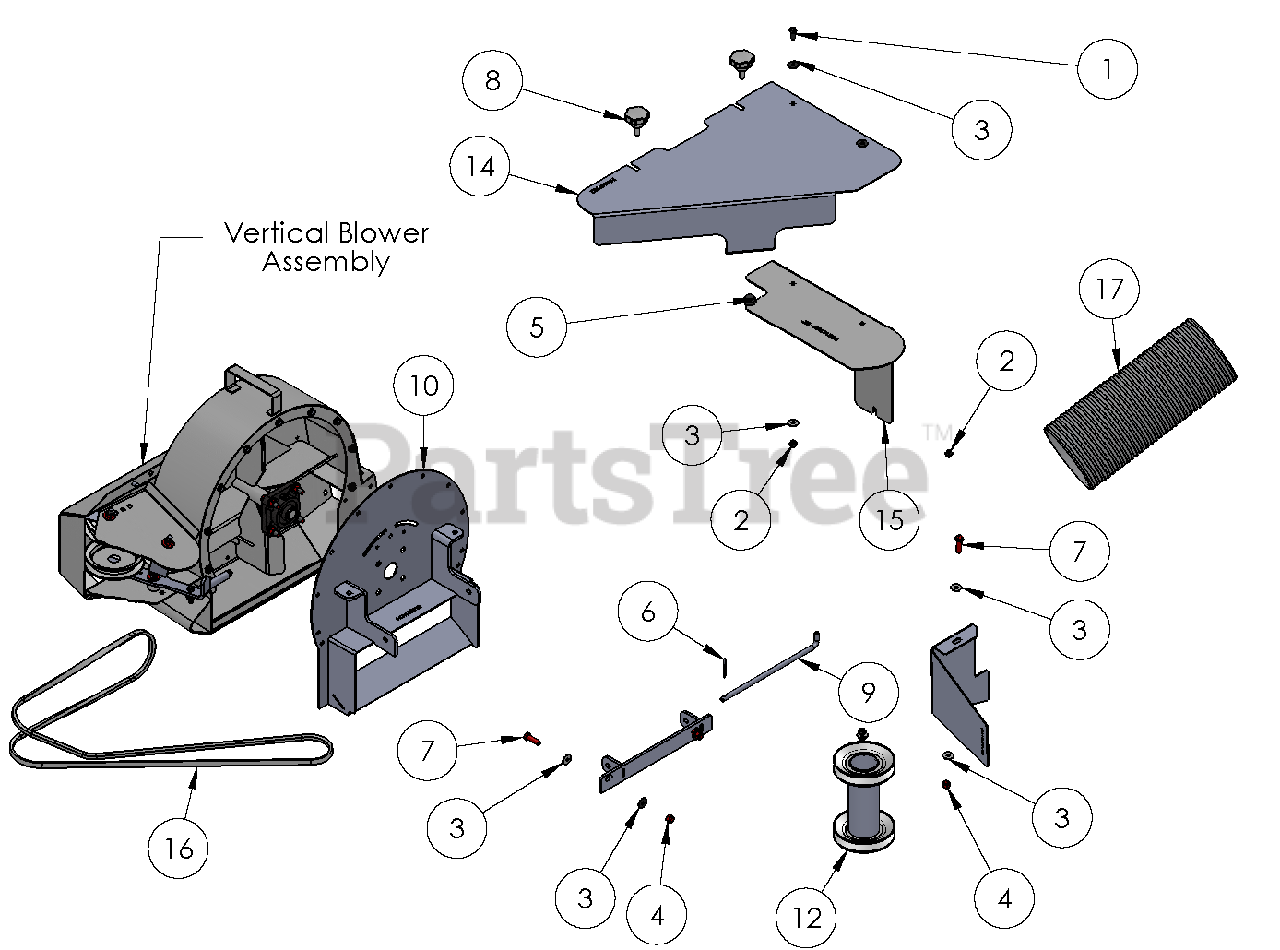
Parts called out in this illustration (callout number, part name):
1	@BLT-HEX .31-18X.75 GR5 YWZC
2	@NUT-LK-NYL-FLG .31-18 YWZC
3	@WSHR-FL-STL.344X.688X.065YWZC
4	@NUT-LK-NYL-FLG .38-16 YWZC
5	RUBBER BUMPER
6	HAIR PIN, 0.091 X 1.875
7	@BLT-HEX .38-16X1.25 GR5 YWZC
8	RELEASE KNOB
9	MOUNTING PIN, 'L' 10.25" EL
10	BLOWER MOUNT, PRO SERIES
11	DECK BRACKET, 66" PRO SERIES
12	DOUBLE PULLEY, PRO SERIES
13	DECK SEAL, 66" PRO SERIES
14	FRONT PULLEY COVER, PRO SERIES
15	PULLEY COVER LEG , 60" PRO
16	BELT, ARAMID CORD 103"
17	HOSE, 6" X 48" LG.
